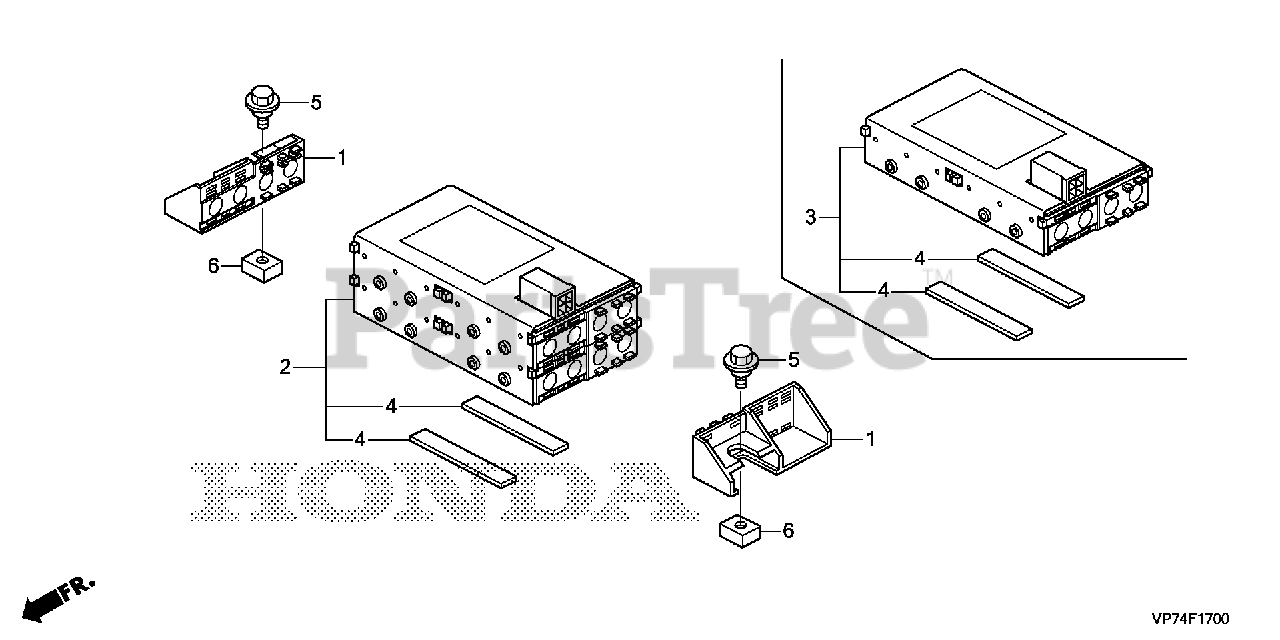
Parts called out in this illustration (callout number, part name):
1	PLATE, BATTERY SETTING
2	BATTERY ASSY. (2P) (MSDS)
4	MAT B, SPLASH GUARD
5	BOLT, FLANGE (6MM)
6	NUT, SPECIAL (6MM)
